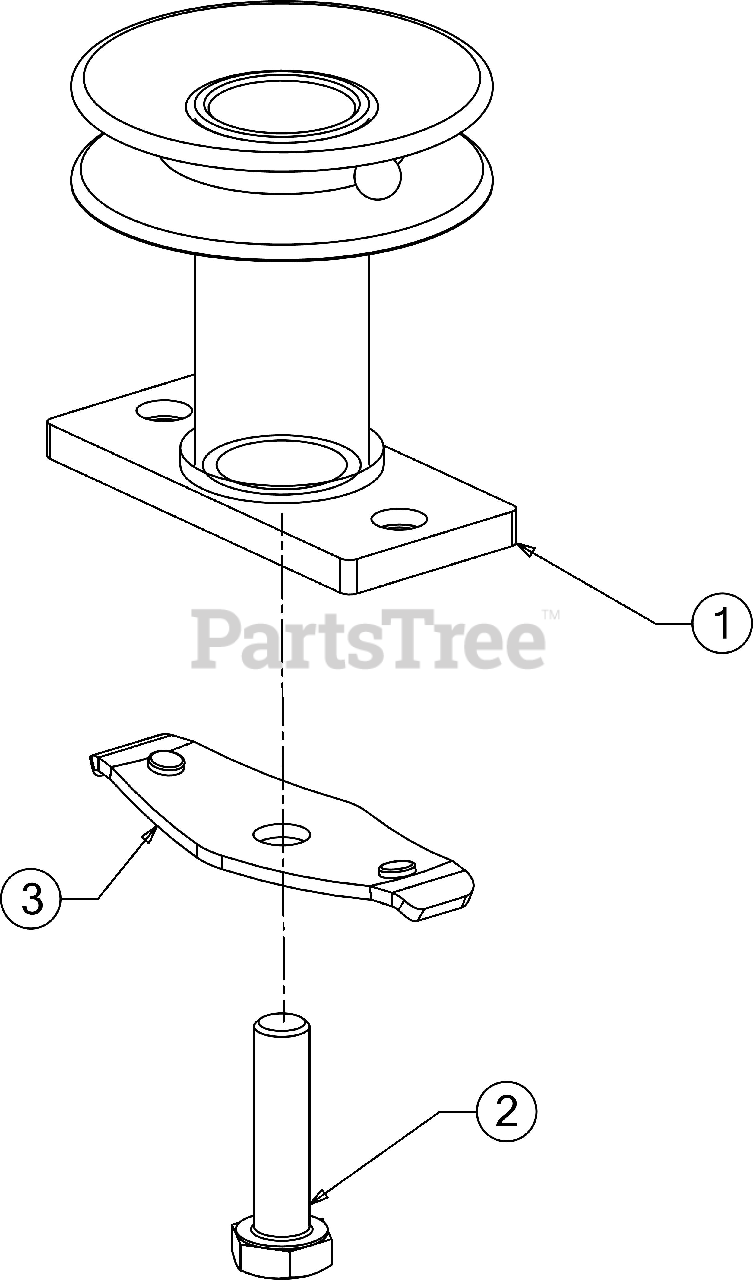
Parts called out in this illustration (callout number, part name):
1	ADAPTER ASSEMBLY (25MM ID X 2.66)
2	SCREW 3/8-24 X 1.50 GR8
3	BLADE BELL SUPPORT
